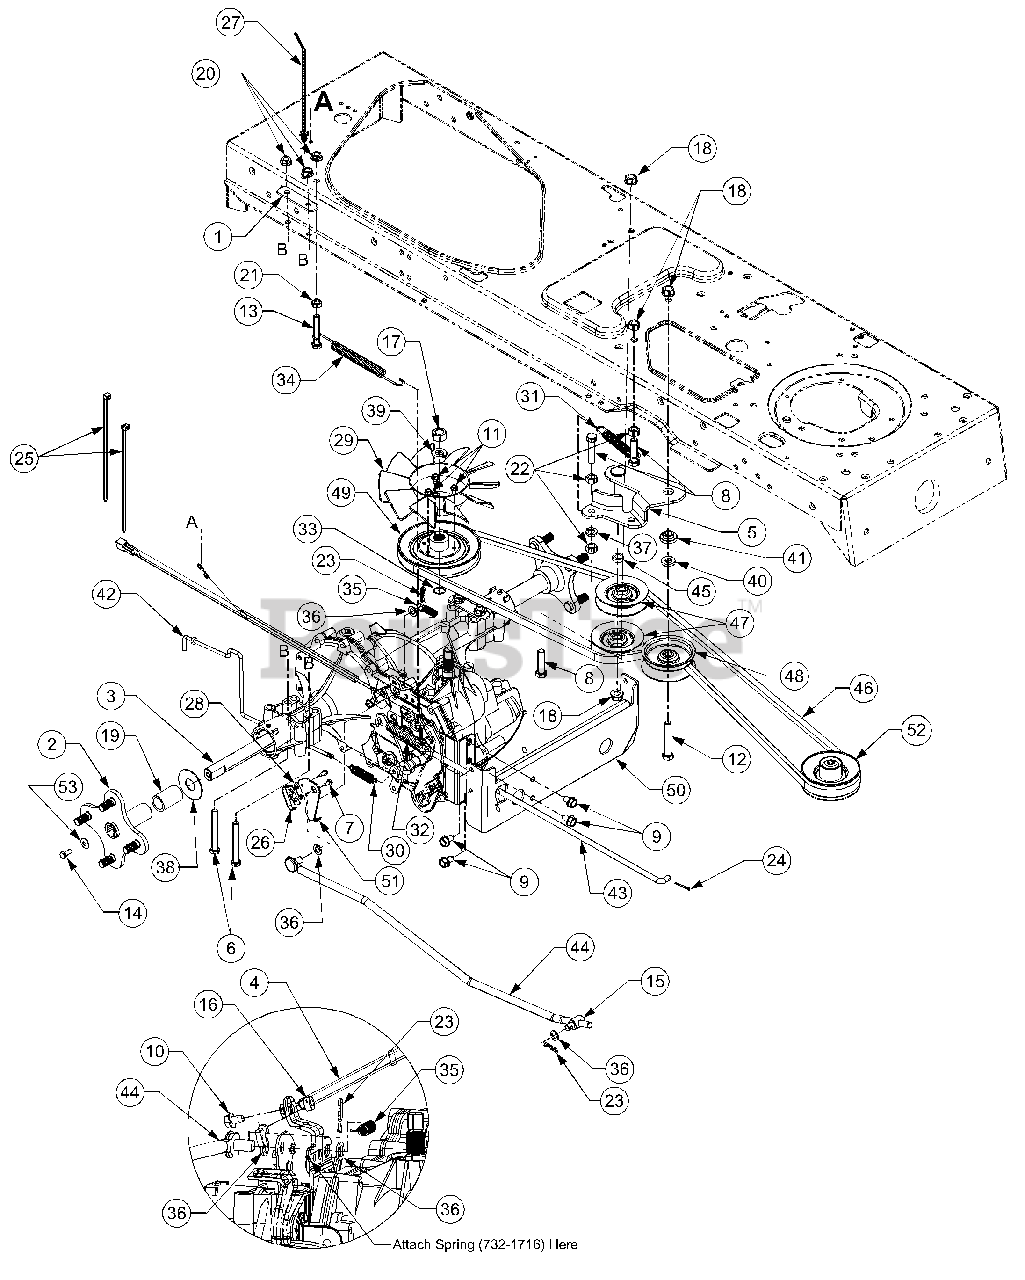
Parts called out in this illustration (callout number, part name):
2	Hub Assembly, Wheel (Double "D")
3	Transmission, Hydrostatic (Uses Double "D" axle)
4	Harness Assembly, Ground & Reverse
6	Hex Cap Screw, 5/16-18,3.5, Gr5
7	Screw, #8-18, 0.500
8	Hex Cap Screw, 3/8-16, 1.50, Gr5
9	Screw, 5/16-12, 0.75
10	Screw, 1/4-20, 0.5
11	Screw, #12-24, 0.375
12	Hex Cap Screw, 3/8-16, 2.25, Gr5
13	Hex Cap Screw, 5/16-18, 2.00, Gr5
14	Hex Cap Screw, 5/16-24 x .750 (Use with Double "D" hub
15	Ferrule, 3/8-24 x .375 Dia
16	Nut, Hex Lock, 1/4-20
17	Nut, Hex, 1/2-20, Gr2
18	Nut, Nylon Lock, 3/8-16
19	Sleeve, 1.5"
20	Nut, Nylon Lock, 5/16-18, Gr5
21	Nut, Hex, 5/16-18, Gr5
22	Nut, Hex, 3/8-16, Gr8
23	Pin, Cotter, .072 Dia. x 1.13 Lg
24	Pin, Cotter, 3/32, 1.0
25	Cable, Tie, 3/16 x .05 x 7.4
26	Switch, Spring, Short
27	Tie, Cable, Push Mount 7.5 Lg
28	Plate, Insulator Nut
29	Fan, Blade, 10"
30	Spring, .48 OD x 2.03 Extension
31	Spring, Extension, .50 Dia x 3.97 Lg
32	Spring, Extension, .59 OD x 4.00 Lg
33	Ring, Wire
34	Spring, Extension, .500 Dia x 7.0 Lg
35	Spring, Extension, 3/8 OD x 1.44 Lg
36	Washer, Flat, .385 x .62 x .063
37	Washer, Lock, 3/8, Regular Duty
38	Washer, Flat, .755 x 1.92 x .060
39	Washer, Lock, 1/2, Regular Duty
40	Washer, Flat, .407 x .812 x .135 Hdn
41	Spacer, Shoulder, 1.00 x .38 x .38
42	Rod, Hydro Bypass
43	Rod, Brake, Hydro
44	Rod, Control, Hydro
45	Spacer, .376 ID x .625 OD x .22
46	Belt, V Type, Poly Ax 79.2 Lg
47	Pulley, Idler, V Type x 3.06 Dia
48	Pulley, Idler, Flat 2.75 OD
49	Pulley, Input, 5.0 Dia S/N 1A174H20368 & before
52	Pulley, Engine, 3.56 Dia.
53	Belle Washer
